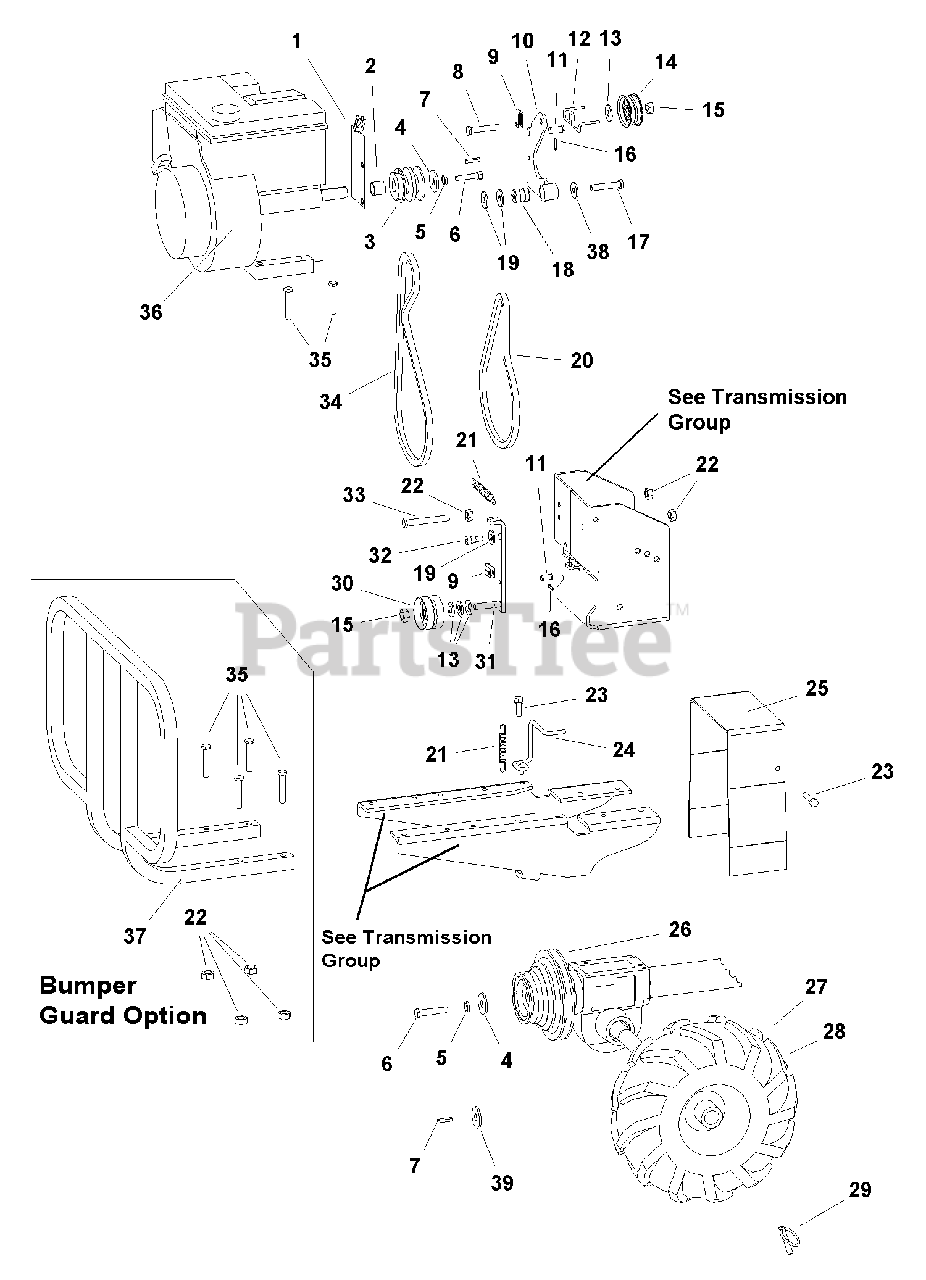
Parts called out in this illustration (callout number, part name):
1	BRACKET, Engine
2	SPACER, Engine
3	PULLEY, Engine 2 Groove
5	LOCKWASHER, Spring, 5/16
6	CAPSCREW, Hex Head, 5/16-24 x 3/4
7	KEY, PARALLEL PLN, 3/16 x 3/16 x 1-3/32
8	CAPSCREW, Hex Head, 3/8-24 x 2
9	YOKE, Cable
11	PIN, Link Forward/Reverse
12	GUIDE, Belt Reverse
13	WASHER, 3/8
14	PULLEY, Idler Reverse
15	NUT, Hex Center Lock, 3/8-16
16	PIN, Cotter
17	BOLT, Flat Head, 5/16-24 x 1-1/2
19	WASHER, 5/16
20	V-BELT, Forward
21	SPRING, Idler Arm
22	NUT, Hex Flange Lock, 5/16-18
23	BOLT, Hex Flange Head, 5/16-18 x 3/4
24	GUIDE, Belt Forward
25	COVER, Belt
26	PULLEY, Transmission 2 Groove
27	WHEEL & TIRE ASSEMBLY TILLER, Left
28	WHEEL & TIRE ASSEMBLY TILLER, Right
29	PIN, Lock
30	PULLEY, Forward Idler
31	ARM, Idler Forward
32	SCREW, Hex Socket Shoulder, 5/16-18 x 3/8
33	CAPSCREW, Hex Head, 5/16-18 x 3-1/2
34	V-BELT, Reverse
35	CAPSCREW, Hex Head, 5/16-18 x 1-3/4
36	* ENGINE, 6HP Briggs & Stratton INTEK
37	** BUMPER, Guard
